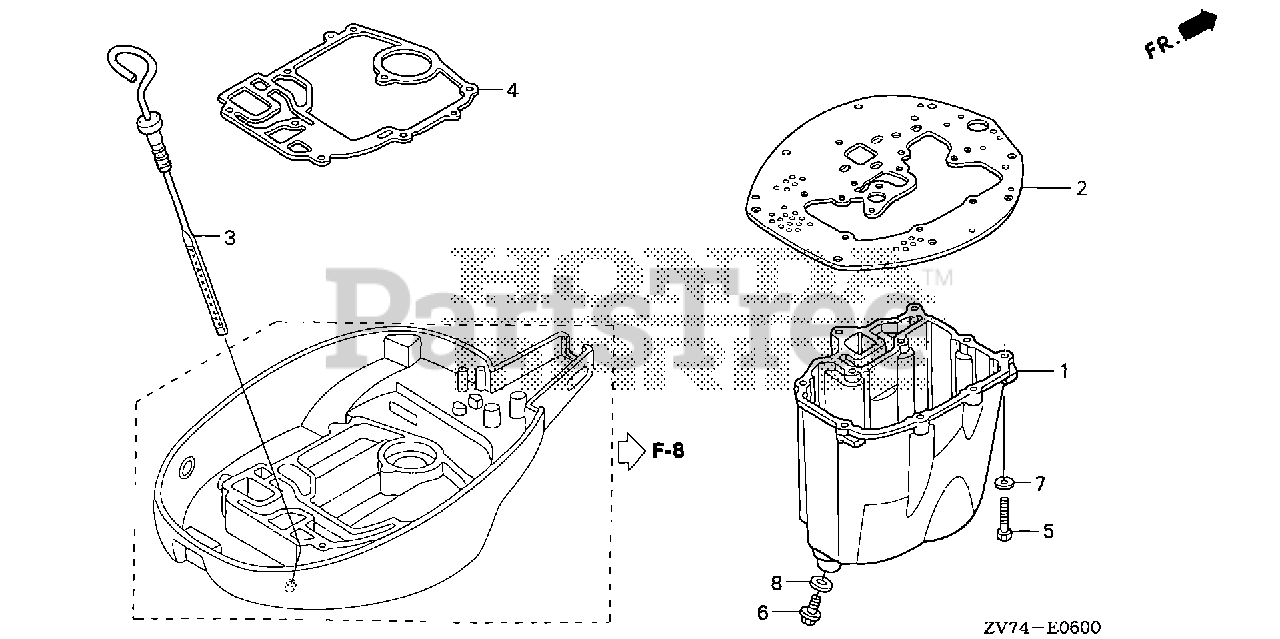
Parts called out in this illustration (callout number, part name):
1	PAN, OIL *TGRAY* (GRAY)
2	GASKET, OIL PAN
3	DIPSTICK, OIL
4	GASKET, ENGINE CASE (LOWER)
5	BOLT, HEX. (6X25)
6	BOLT, DRAIN PLUG
7	WASHER, PLAIN (6MM)
8	WASHER, DRAIN PLUG (12MM)
